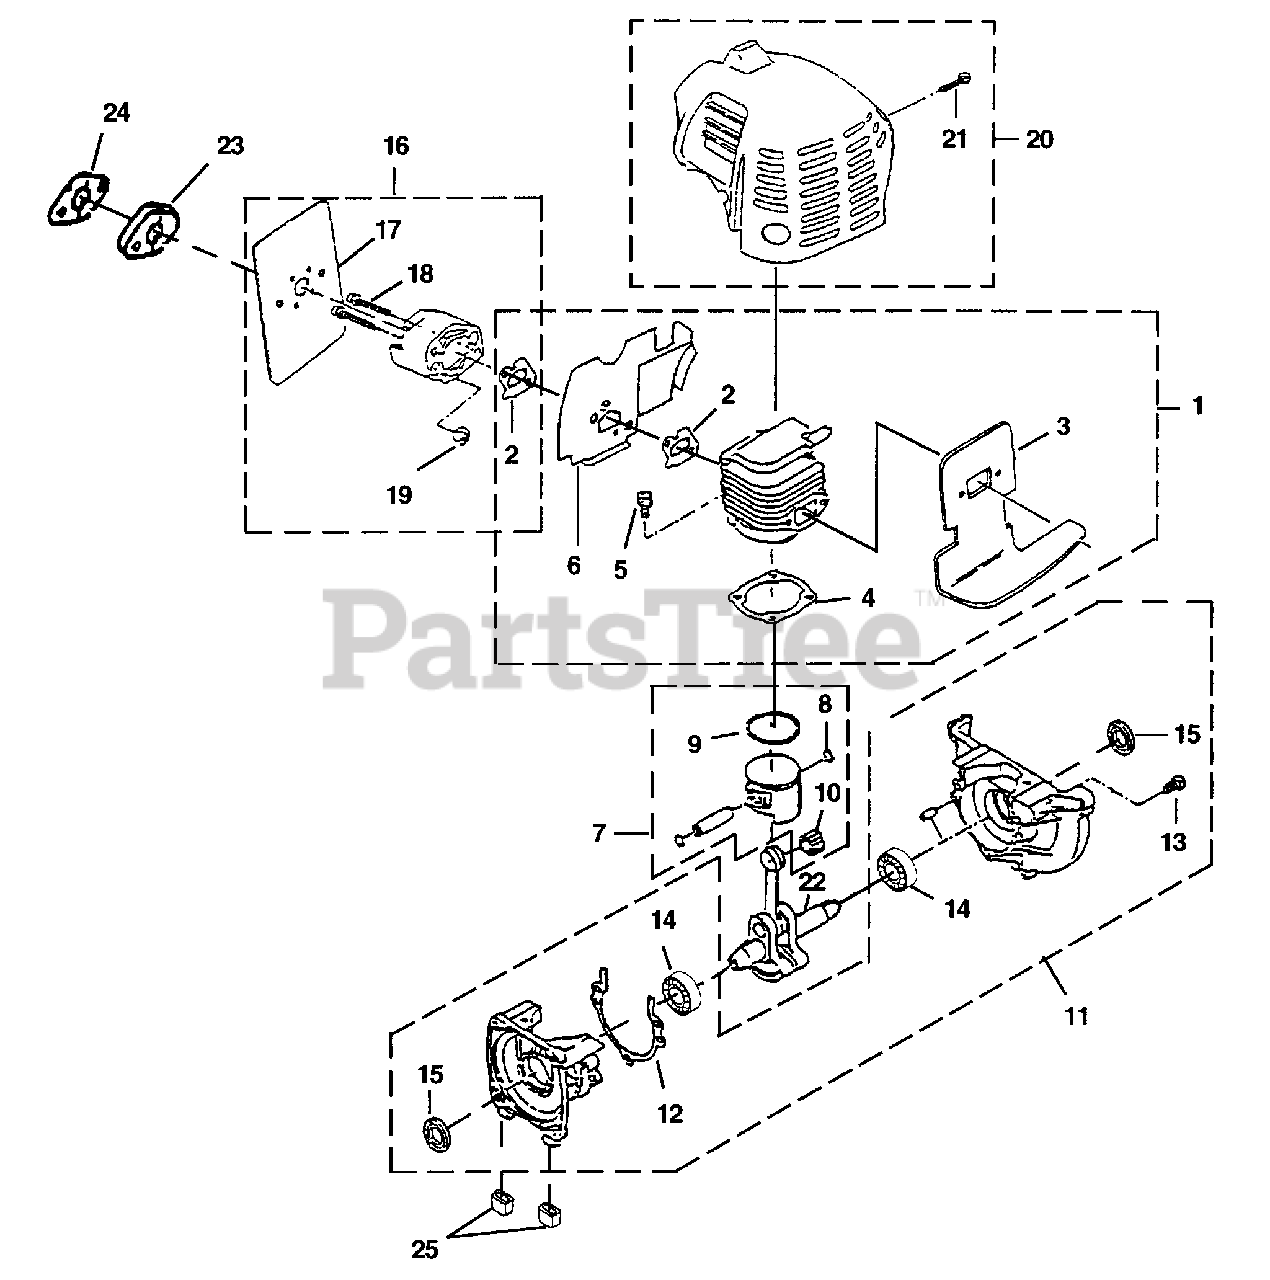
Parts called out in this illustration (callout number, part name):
1	CYLINDER ASSEMBLY
2	GASKET-Heat Dam
3	GASKET-Muffler
4	GASKET-Cylinder
5	SCREW-Socket HD (M5 x 20 SW)
6	INSULATOR-Carburetor
7	PISTON ASSEMBLY
8	RING-Retaining
9	RING-Piston
10	BEARING-Wrist Pin
11	CRANKCASE ASSEMBLY
12	GASKET-Crankcase
13	SCREW
14	BALL BEARING
15	OIL SEAL
16	HEAT DAM ASSEMBLY
17	GASKET-Carburetor
18	SCREW-Socket Hd
20	CYLINDER COVER
21	SCREW (M5 X 14)
22	CRANKSHAFT
23	CARBURETOR SPACER
24	GASKET, AIR CLEANER
25	ISOLATOR KIT
